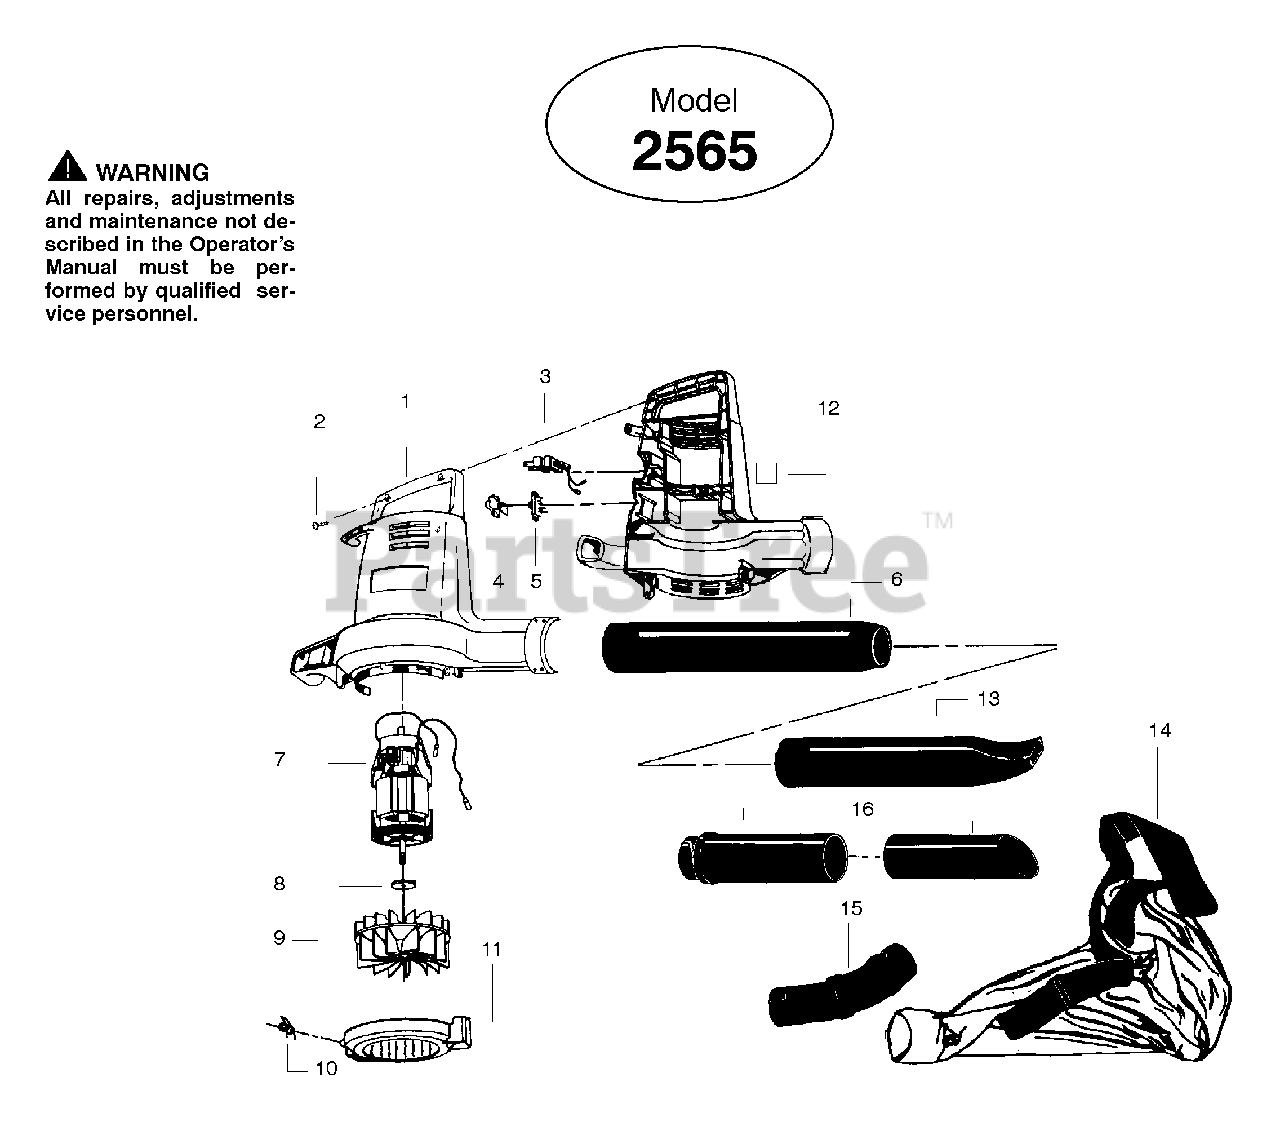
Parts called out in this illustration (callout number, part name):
1	Housing Set
3	Wire Harness
4	Switch Cover
6	Blower Tube
7	Motor Ass'y.
9	Impeller
11	Inlet Cover
14	Vacuum Bag Kit
16	Vacuum Tube Kit
